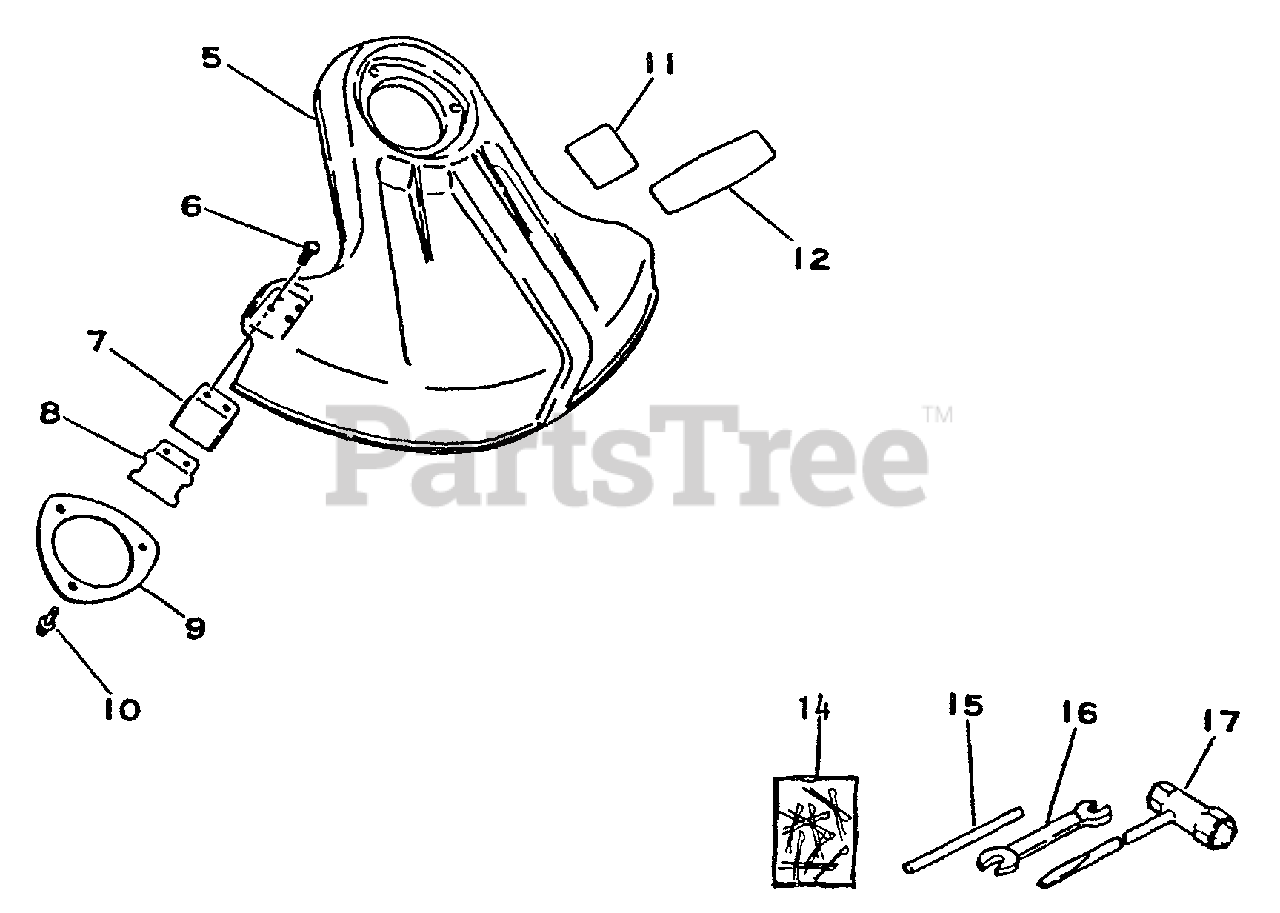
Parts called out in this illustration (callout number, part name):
5	SHIELD ASSY
6	SCREW 5×16
7	KNIFE, TRIMMER LINE
8	PROTECTOR
9	PLATE, SHIELD Ø49.5 MM
10	SCREW 5×16
11	LABEL - CAUTION
12	LABEL - ECHO
14	PIN, COTTER 2×22 (PKG. OF 10)
15	TOOL, LOCKING 5×120 MM
16	SPANNER 8×10
17	T-WRENCH 17x-19 L200
